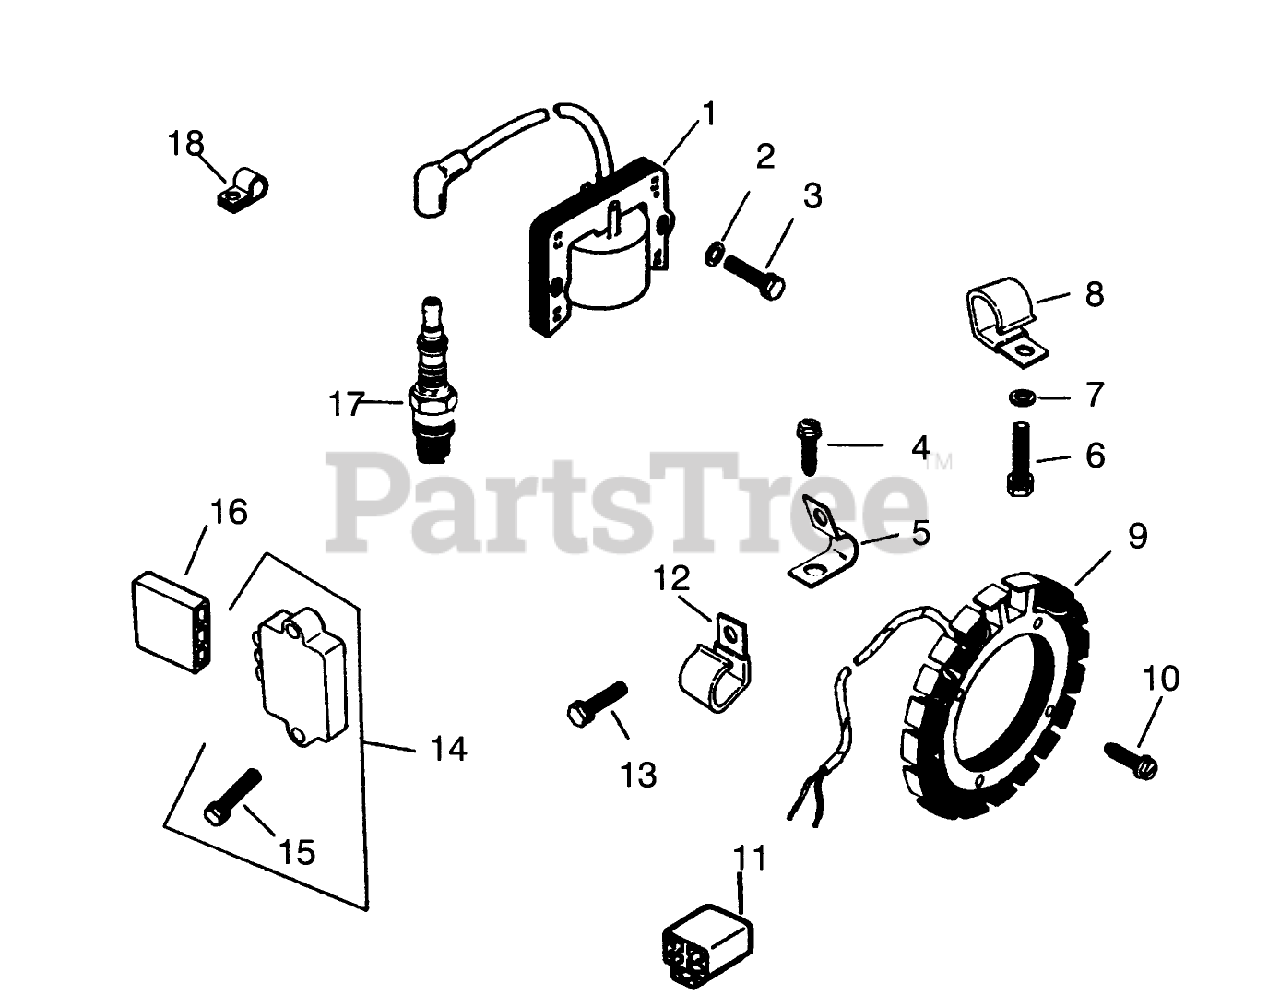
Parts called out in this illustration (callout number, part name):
1	KOHLER 47-584-02
2	KOHLER X-25-79
3	KOHLER X-156-1
4	KOHLER X-67-59
5	KOHLER X-728-1
6	KOHLER X-67-83
7	KOHLER X-25-72
8	Clip
9	KOHLER 237878
10	KOHLER X-67-51
11	KOHLER 48-155-01
12	CLIP
13	SCREW-HH
14	KOHLER 41-403-05
15	KOHLER X-132-4
16	KOHLER 236602
17	KOHLER 235041-5
18	KOHLER 210281
